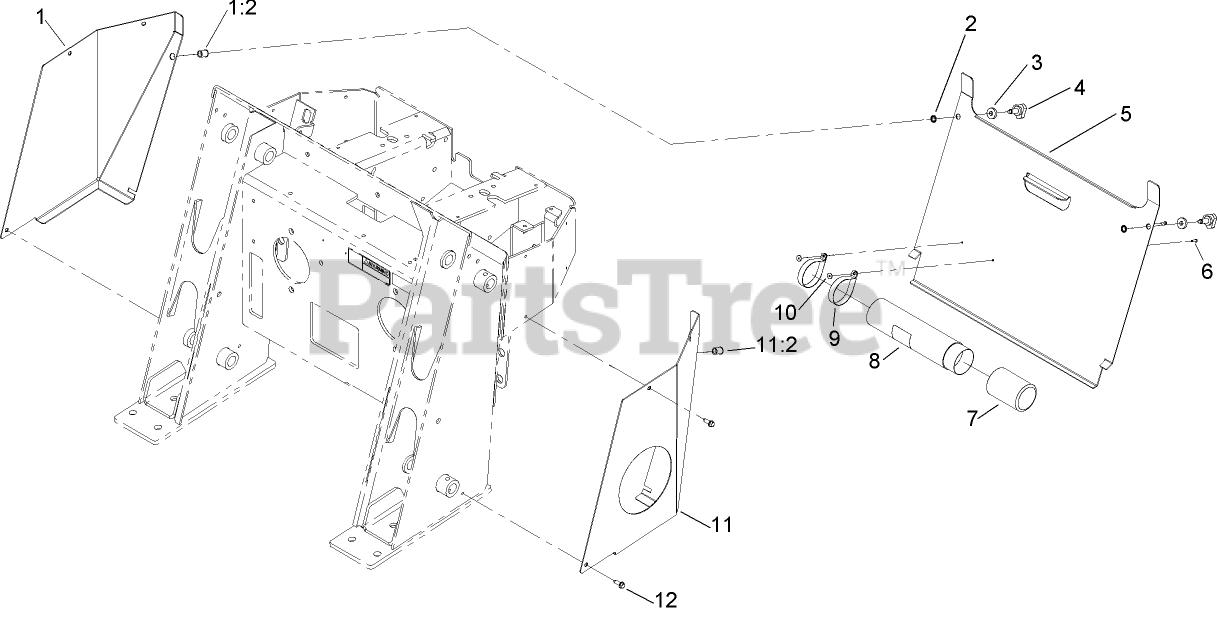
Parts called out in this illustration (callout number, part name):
1	RH REAR COVER SUPPORT ASM
1:2	INSERT-NUT
2	RING-RETAINING
3	WASHER-RUBBER
5	COVER-ACCESS, REAR
6	RIVET-POP
7	CAP-HOUSING
8	TUBE-MANUAL
9	CLAMP-R
10	WASHER-BACK
11	LH REAR COVER SUPPORT ASM
11:2	INSERT-NUT
12	SCREW-HWH
